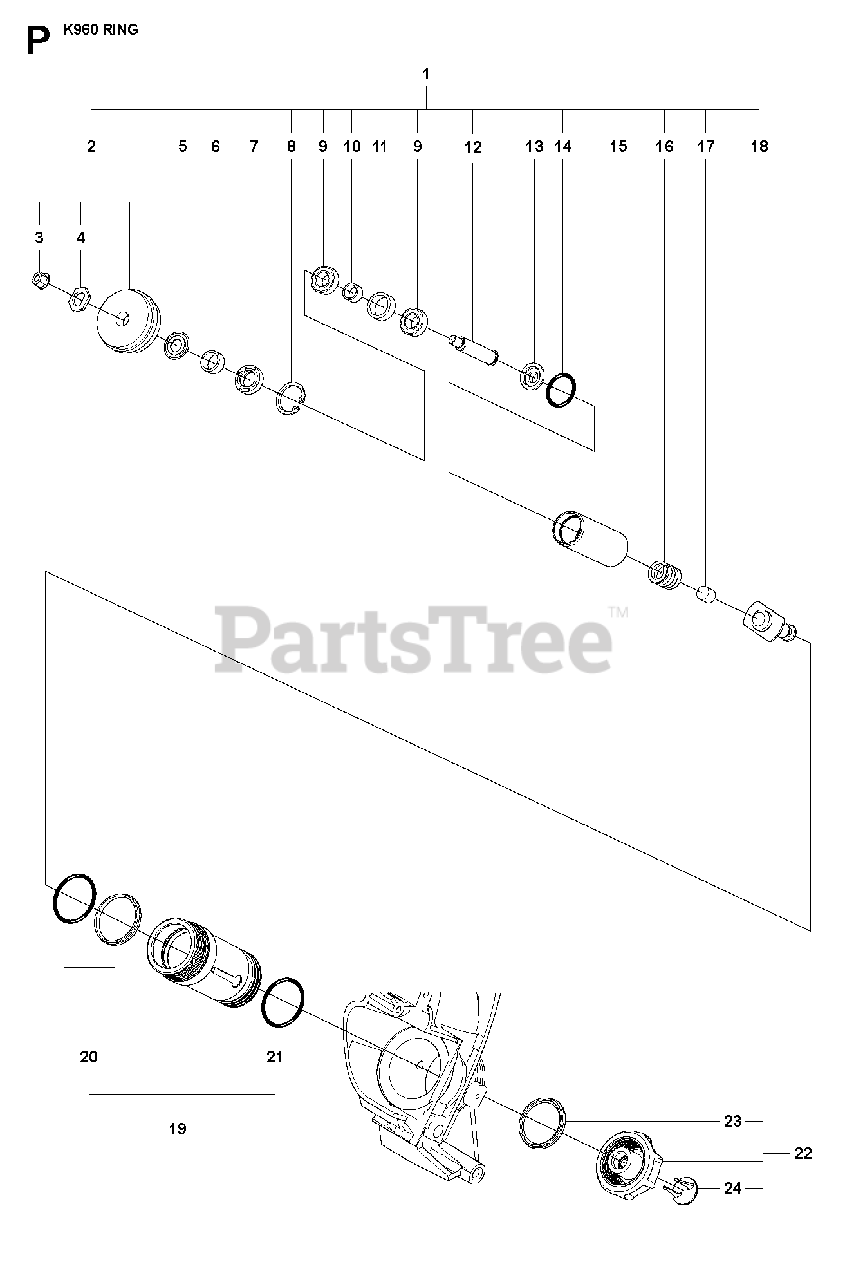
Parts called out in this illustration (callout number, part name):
1	BEARING CAGEIncl. 2, 5 - 18
1	BEARING CAGEIncl. 2, 5 - 18. Sweden only
2	GUIDE ROLLERIncl. 3, 4
9	BALL BEARING
19	SLEEVEIncl. 20, 21
